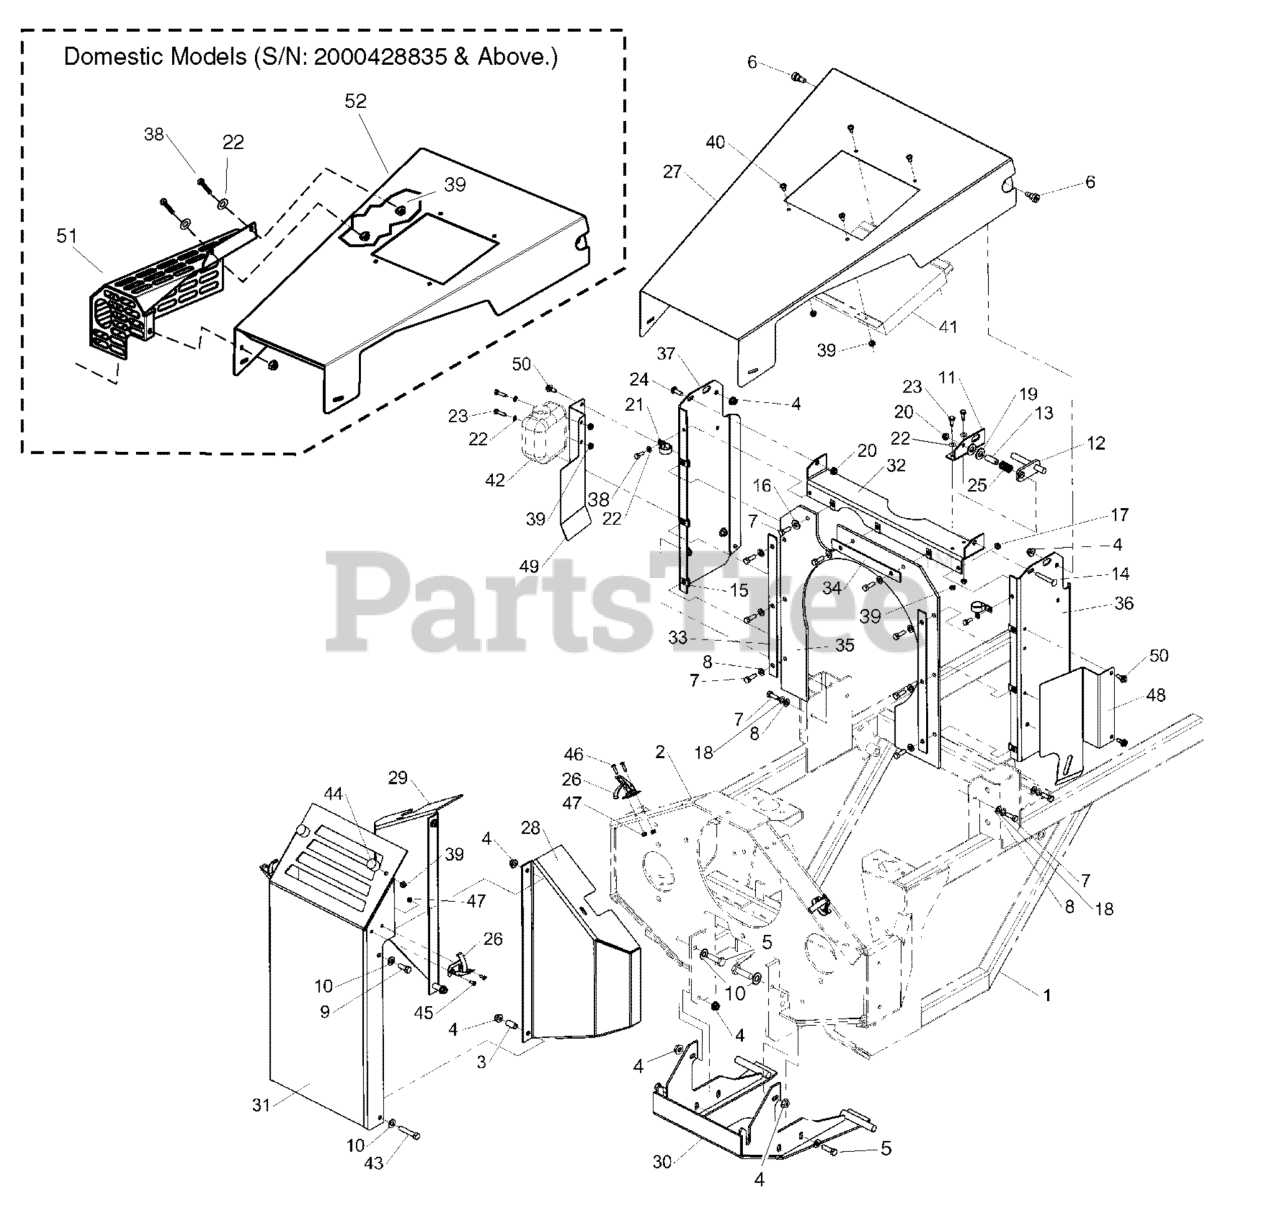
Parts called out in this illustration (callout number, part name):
1	MAIN FRAME
2	PUMP PLATE
3	SPACER, .38 X .50 X 1.00
4	NUT, 3/8-16 HEX NYLOCK FLANGE
5	BOLT, 3/8-16 X 1-1/4" GD5 CZ
6	BOLT, 3/8-16 X 3/8", 1/2" SHOULDER
7	BOLT, 5/16-18 X 1" GD5 YZ
8	WASHER, 5/16" SAE
9	BOLT, 3/8-16 X 1" GD5 CZ
10	WASHER, 3/8 SAE
11	PLATE, HOOD SUPPORT, HOLDER
12	WELD, HOOD LATCH
13	SPACER, .38 X .50 X 1.25, CZ
14	BOLT, 5/16-18 X 2-1/4", CARRIAGE
15	BODY CLIP, 5/16-18-7GA MATERIAL
16	WASHER, .34 X 1.25 X 10 GA
17	NUT, 1/4-20 HEX SERR. FLANGE
18	WASHER, 5/16 LOCK CZ
19	WASHER, 1/2 SAE
20	NUT, 5/16-18 HEX NYLOCK FLANGE
21	CLAMP, 5/16 DOUBLE, WIRE & TUBE
22	WASHER, 1/4 SAE
23	BOLT, 1/4-20 X 3/4" GD5 YZ
24	BOLT, 5/16-18 X 3/4", CARRIAGE
25	SPRING, HOOD LATCH
26	LATCH, HOOD
27	HOOD
28	WELD, BUMPER SIDE RH
29	WELD, BUMPER SIDE LH
30	WELD, SKID PLATE
31	WELD, BUMPER CENTER
32	BRACE, SHROUD
33	BAR, RUBBER SUPPORT SIDE
34	BAR, RUBBER SUPPORT TOP
35	SHROUD, RUBBER
36	SHROUD UPRIGHT, RH
37	SHROUD UPRIGHT, LH
38	HHCS, 1/4-20 X 0.625, GR5, ZINC/CLEAR
39	NUT, 1/4-20 HEX NYLOCK FLANGE
40	SCREW, 1/4-20 X 1/2" ALLEN BH
40	SCREW, 1/4-20 X 1" ALLEN BH
41	OIL COOLER
42	EXPANSION TANK
43	BOLT, 3/8-16 X 2, GD5, CZ
44	BUMPER, RUBBER 1/4-20
45	SCREW, #10-24 x 1/2"
46	SCREW, #10-24 X 3/4"
47	NUT, #10-24 Hex Nylon Lock
48	GUARD, FAN, RH - RED
49	GUARD, FAN, LH - RED
50	BOLT, 5/16-18 X 3/4", SELF-TAPPING
51	WELD, MUFFLER GUARD, IS4500Z -RED
52	WELD, HOOD, IS4500Z - RED
